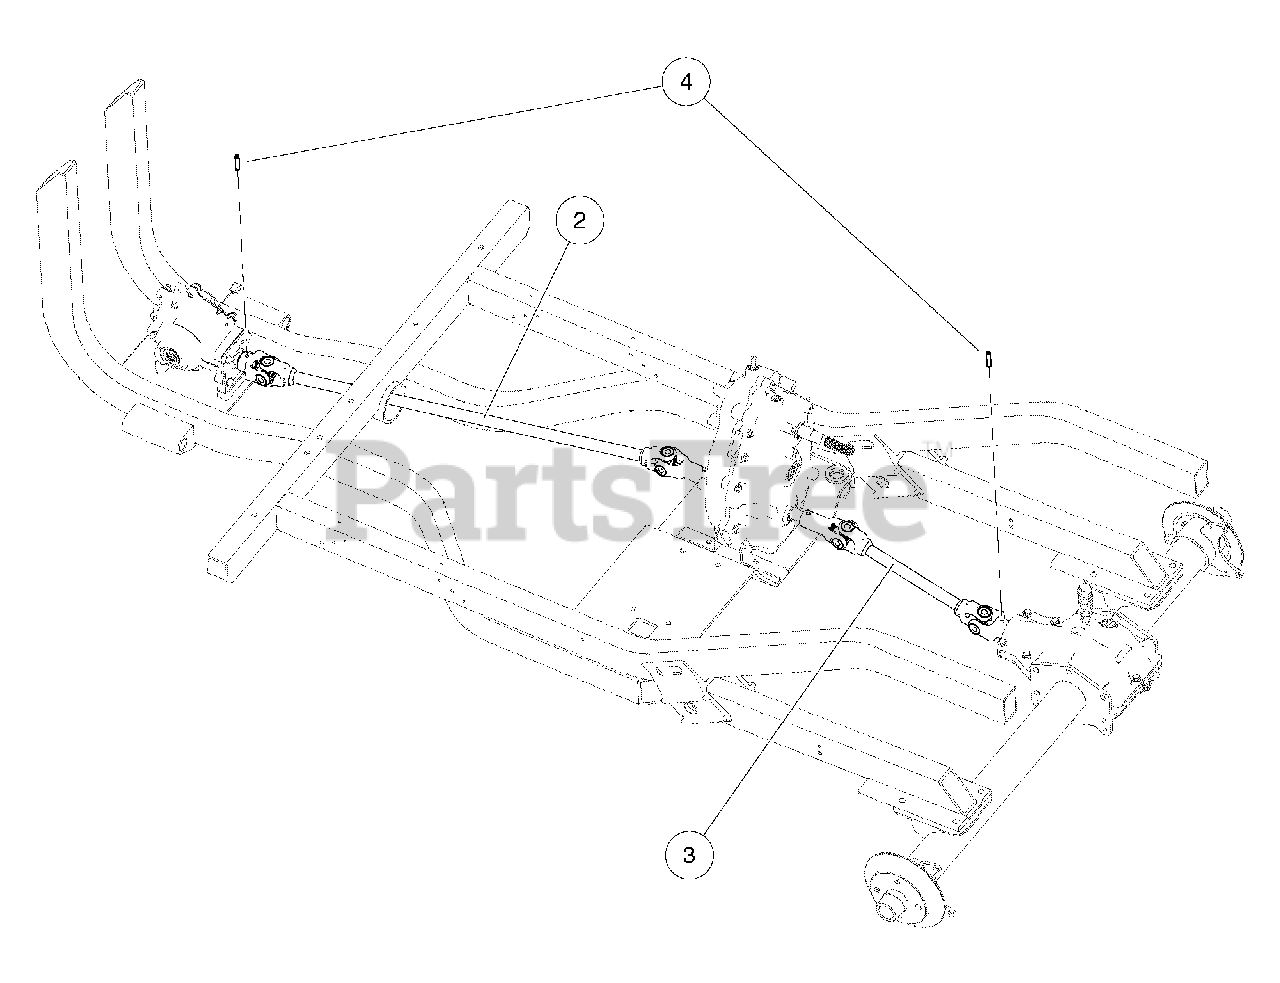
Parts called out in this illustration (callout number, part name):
1	Inst, Prop Shafts, Awd
2	Prop Shaft, Front
3	Prop Shaft, Rear
4	Pin, Spring, 5/16 X 1-1/2 Hd
